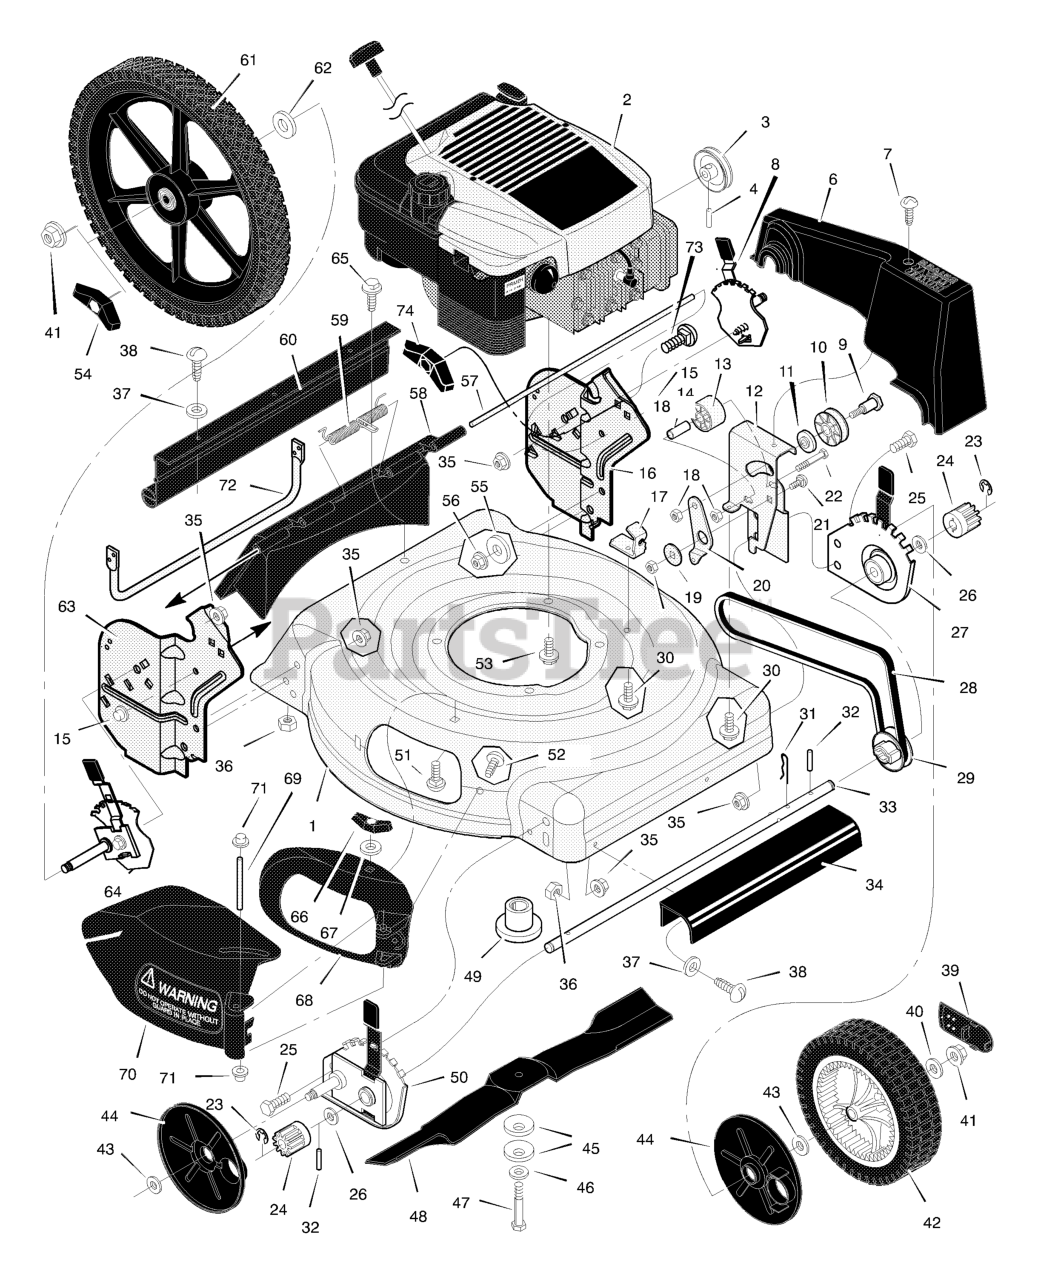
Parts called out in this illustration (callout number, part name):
1	Housing
2	Engine *
3	Pulley, Engine
4	Pin, Spring
6	Cover, Belt (Black)
8	Adjuster, Left Rear Height
9	Bolt, Shoulder
12	Bracket, Idler Support
13	Pulley, Idler
14	Bearing
15	Nut, Push
16	Bracket, Left Handle
17	Bracket, Cable
18	Nut, Hex
20	Arm, Idler
21	Bolt, Carriage
22	Bolt, Shoulder
24	Gear, Pinion
25	Bolt
27	Adjuster, Left Frt Height
29	Pulley, Axle
31	Pin, Hair
32	Pin, Spring
34	Cover, Axle (Black)
35	Nut, Flange
36	Nut, Hex
39	Hub Cap
40	Washer
41	Nut, Flange
42	Wheel, Drive
44	Cover, Dust
45	Washer, Belleville
49	Adapter, Blade
50	Adjuster, Right Frt Height
51	Bolt, Carriage
53	Bolt, Engine
55	Washer
56	Nut, Flange
57	Rod, Pivot
58	Door, Rear (Black)
60	Deflector, Rear
61	Wheel, Rear
63	Bracket, Right Handle
64	Adjuster, Right Rear Height
66	Wingnut
67	Retainer, Push
68	Bezel (Black)
69	Pin, Pivot
70	Deflector, Chute (Black)
71	Push On Cap
73	Bolt, Carriage
